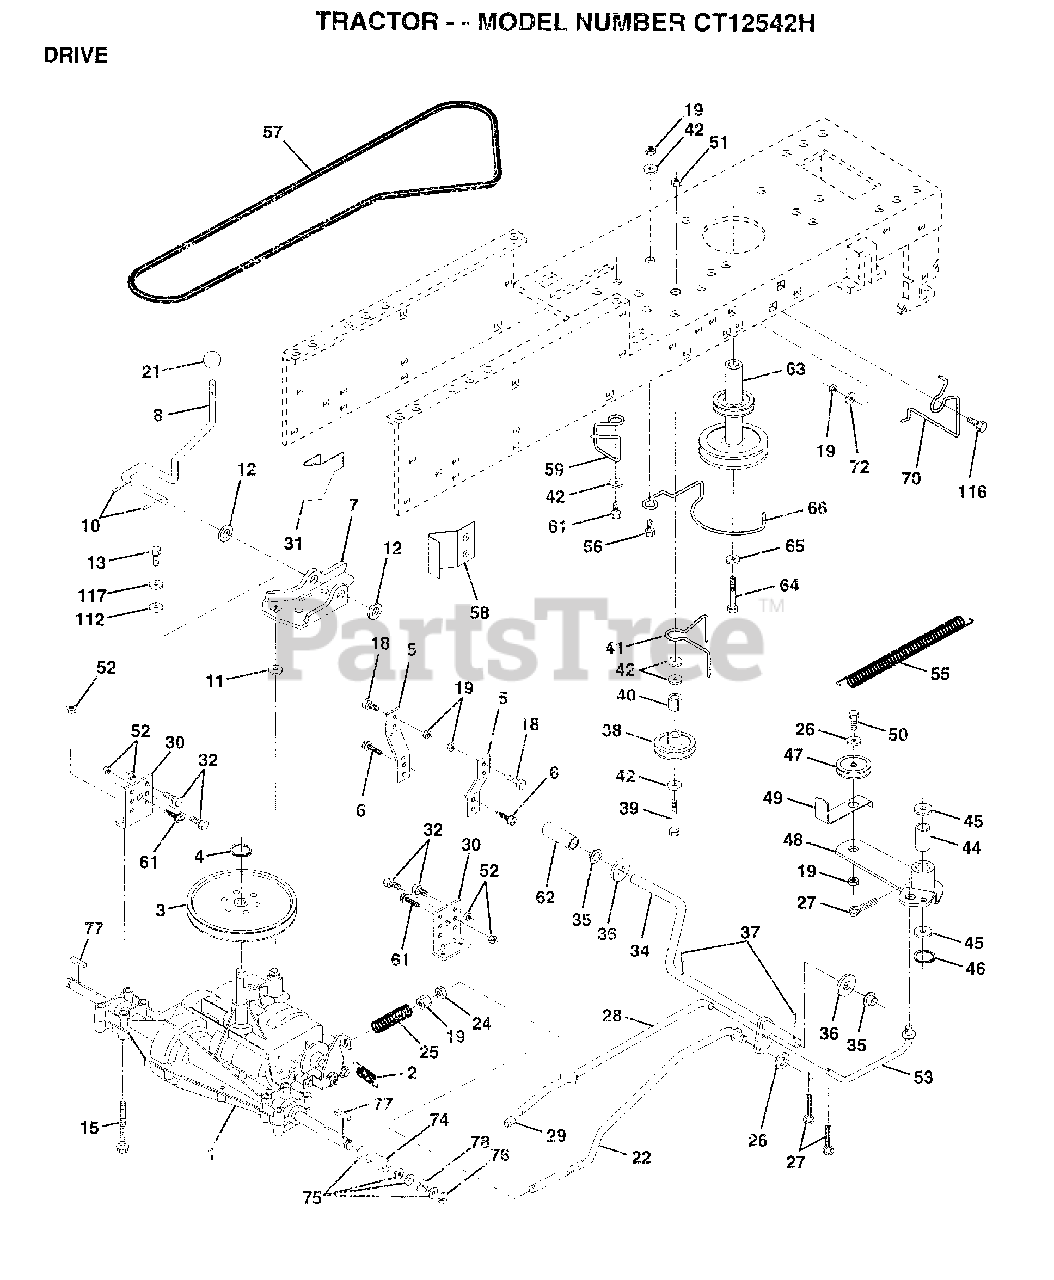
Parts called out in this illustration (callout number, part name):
2	SPRING.BRAKE.RETU
3	PULLEY TRANS
5	STRAP TORQUE
6	SCREW
8	SHIFT ROD
10	PIN COTTER 1/8
11	WASH-SHFT PLT LT
12	WASHER
13	BOLT.1/4-28.W/PAT
14	LOCKWASHER
15	BOLT.HX.FLG.5/16
18	BOLT
19	NUT
21	CONTROL KNOB LT
22	BRAKE ROD
24	NUT
25	SPRING ROD LT
26	WASHER
27	COTTER PIN
28	ROD.BRAKE.PARK.LT
30	TRANSAXLE MTG BKT
31	"KEEPER,BELT LH T"
32	BOLT
34	SHAFT.PEDAL.FOOT
35	NYLON BEARING
36	WASHER LT
38	PULLEY.IDLER.FLAT
39	BOLT
40	SPACER T
41	BELT KEEPER LT
42	WASHER
44	"LY, BEARING"
45	WASHER LT
46	KLIP RING
48	ARM IDLER
49	RETAIN BELT
53	"LINK, CLUTCH T"
55	"SPRING, RETURN LT"
58	"KEEPER,BELT RH T"
59	KEEPER BELT CNTSP
61	SCREW
62	PEDAL COVER T
63	PULLEY.ENGINE
64	BOLT
65	LOCKWASHER
66	KEEPER.BELT.ENG.L
70	KEEPER BELT ENG
72	WASHER
74	SPACER LT
75	WASHER
76	E-RING LT
77	SQUARE KEY
78	WASHER
112	WASHER LT
116	BOLT RDHD 3/8-16
